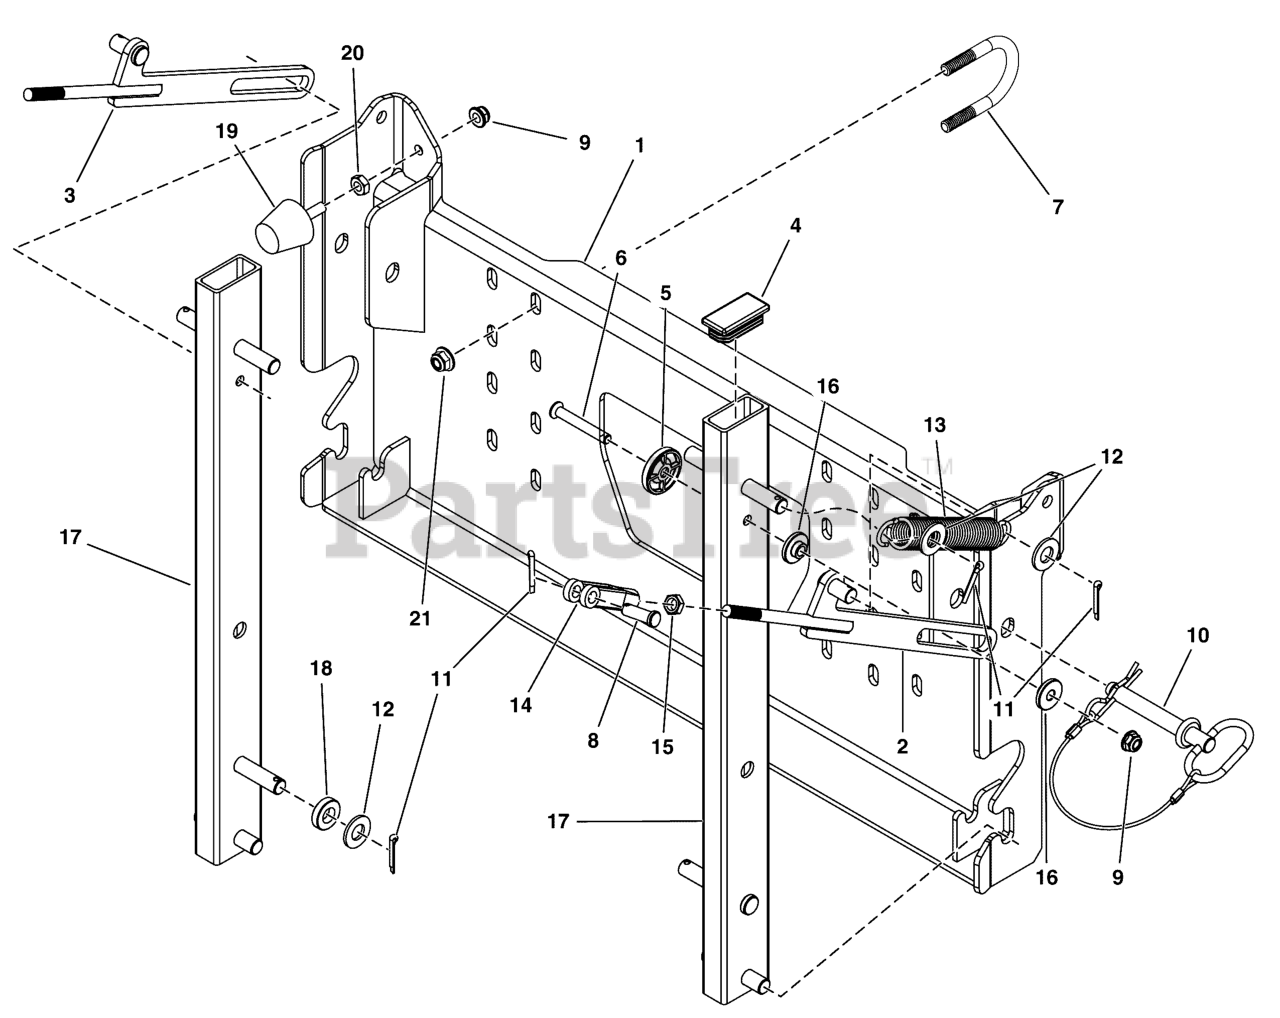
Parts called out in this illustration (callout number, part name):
1	WELD, HOPPER MOUNT, 2200/3300 - BLK
2	WELD, RIGHT LATCH PULL, ZTR - BLK
3	WELD, LEFT LATCH PULL, ZTR - BLK
4	PLUG, 1 X 2, 10-14 GA. TUBING
5	SPACER, .34 X 1.54 X .25 - UHMW
6	SCREW, 5/16-18X2.25, FLAT HEAD SOC, CZ
7	U-BOLT, 3/8" X 1-1/4"
8	PIN, CLEVIS, 3/8 X 1-1/8, PLATED
9	NUT, 5/16-18 HEX NYLOCK FLANGE NUT
10	PIN, HITCH, .50 X 3.25 W/ LAY (SV)
11	PIN, 3/32 X 0.750, COT, ZINC/CLEAR
12	WASHER, 1/2 SAE
13	SPRING, EXTENSION, 1.00
14	CLEVIS, 3/8-24, Plastic
15	NUT, 3/8-24 Hex Jam
16	SPACER,HYDRAULIC LIFT PIVOT
17	WELD, SUPPORT TUBE, HOPPER - BLK
18	SPACER, .52 X 1.00 X .25, CZ
19	BUMPER, RUBBER 5/16-18
20	NUT, 5/16-18 HEX JAM
21	NUT, 3/8 - 16 HEX NYLOCK FLANGE
